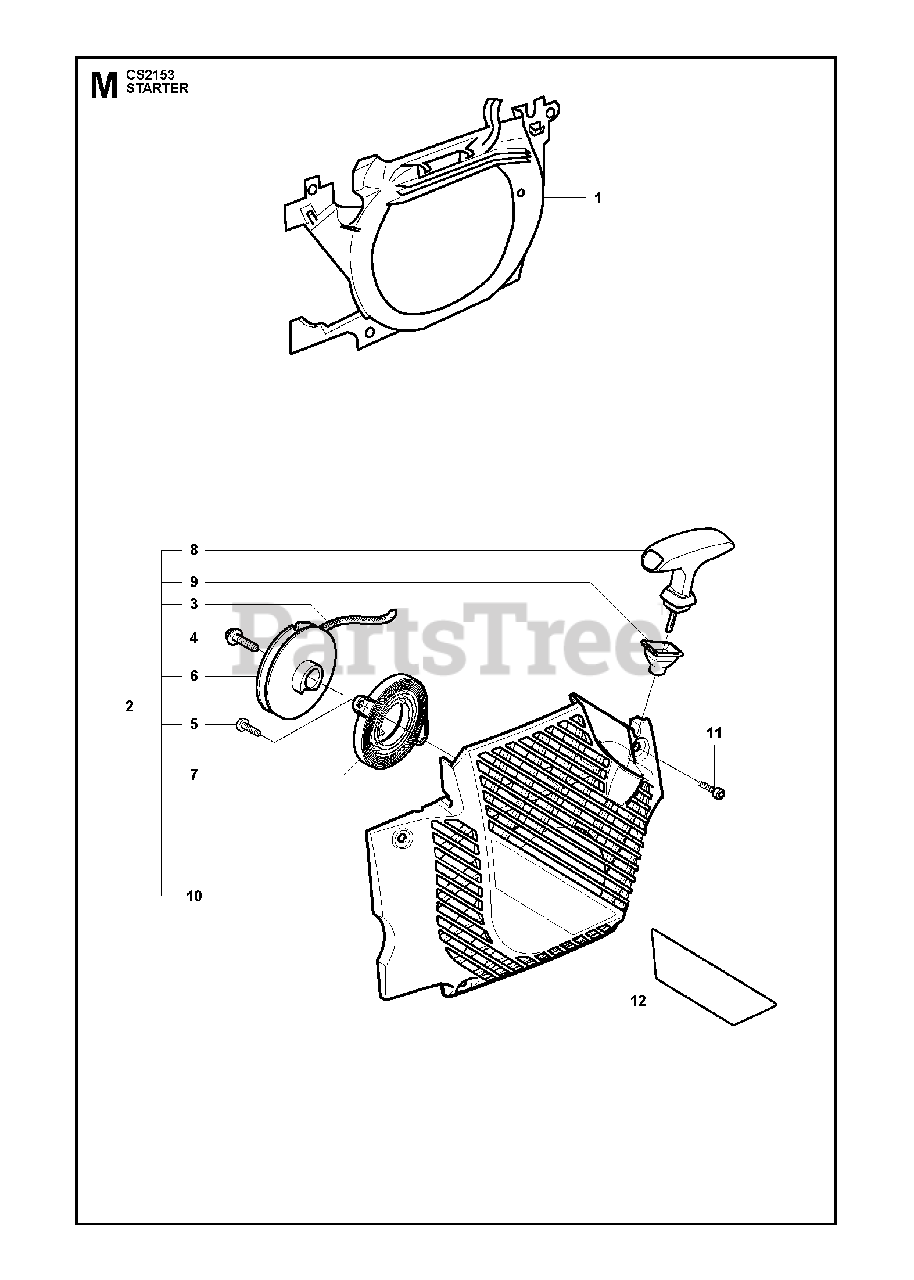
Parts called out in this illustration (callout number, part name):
1	AIR CONDUCTOR
2	STARTER ASSY.
3	STARTER ROPE
4	SCREW
5	SCREW
6	PULLEY
7	RETURN SPRING
8	STARTER HANDLE
9	SLEEVE
10	STARTER HOUSING
12	LABEL
